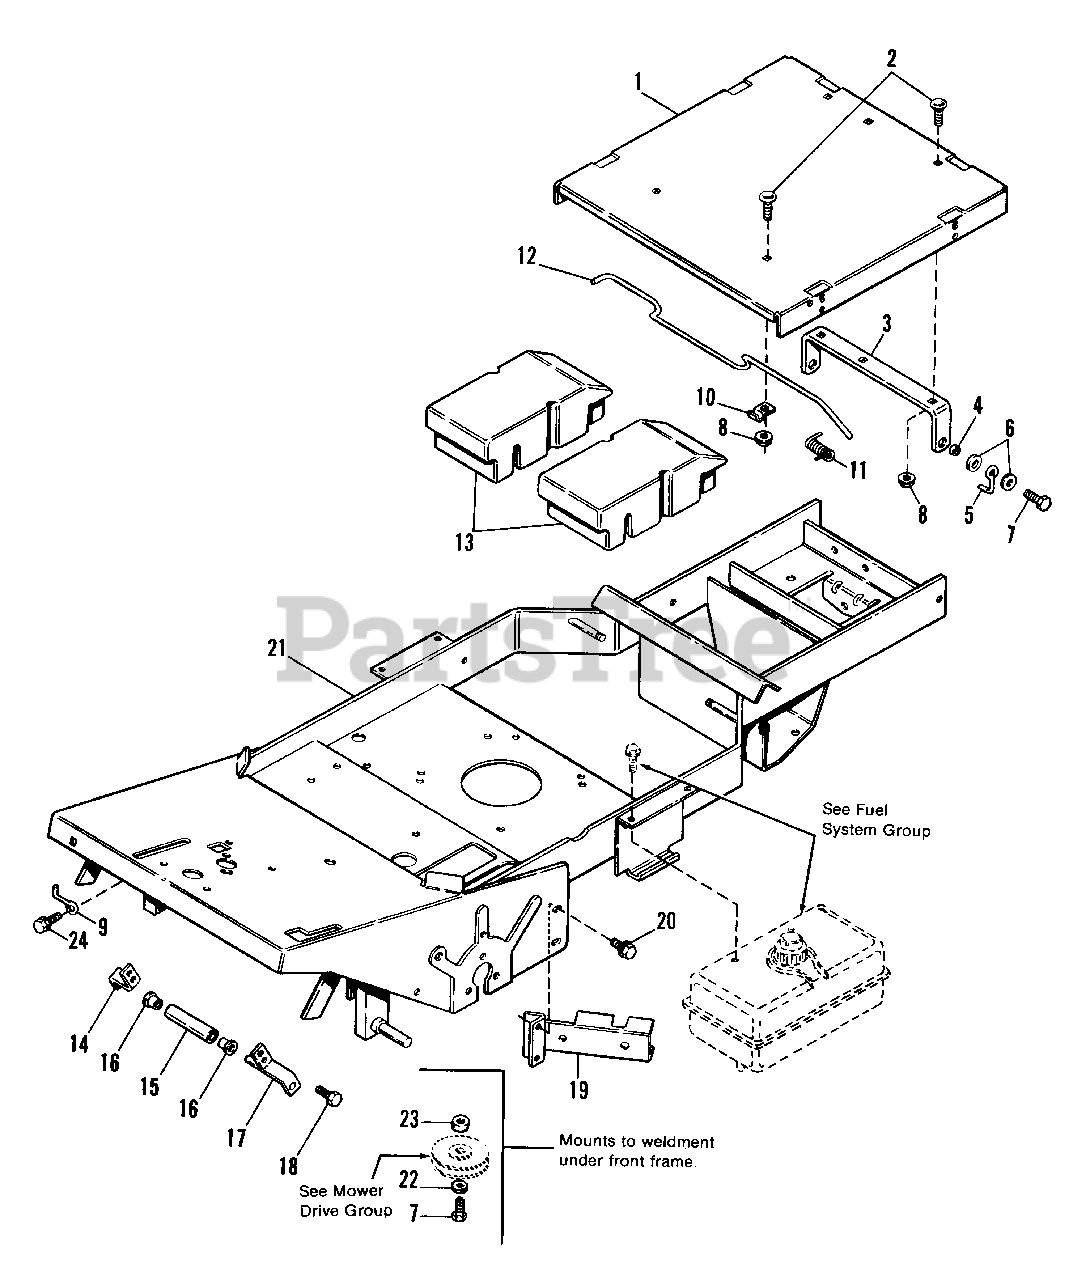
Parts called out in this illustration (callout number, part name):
1	PLATFORM (1691654)
1	PLATFORM (1691658)
2	CARRIAGE BOLT, 5/16-18 x 3/4
3	BRACKET, Pivot
5	STOP, Pivot
6	WASHER, Plain
7	SCREW, Taptite, 5/16-16 x 1-1/4
8	NUT, Hex, Whizlock, 5/16-18
9	RETAINER, Cable
11	SPRING, Torsion
13	WEIGHT, Rear
14	BRACKET, Roller, Front
15	TUBE, Pivot
16	BUSHING, Flanged
17	BRACKET ASSY.
18	SCREW, Taptite, 5/16-18 x 3/4
19	SUPPORT ASSY., GasTank
20	SCREW, Taptite, 5/16-18 x 1/2
21	FRAME ASSY.
22	WASHER, Plain, 3/8
24	SCREW, Taptite, 5/16-18 x 3/4
